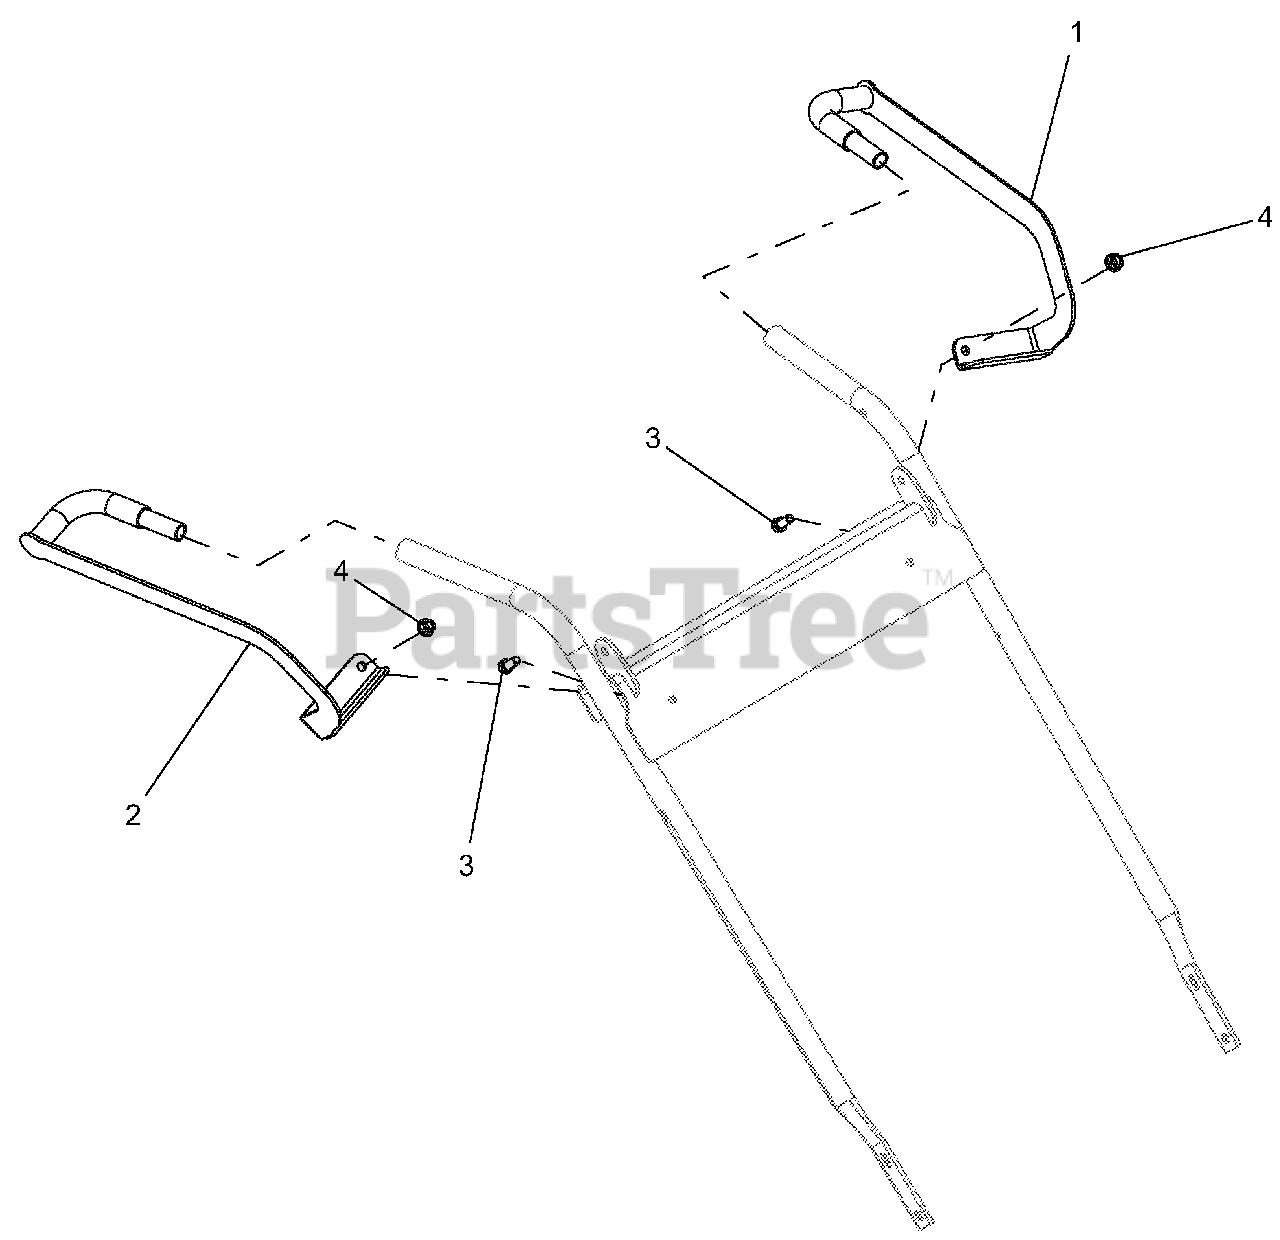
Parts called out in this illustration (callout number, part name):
1	WMT-HWM HANDGUARD, LH
2	WMT-HWM HANDGUARD, RH
3	@BLT-HEX .31-18X.75 GR5 YWZC
4	@NUT-LK-TOP-FLG .31-18 YWZC
